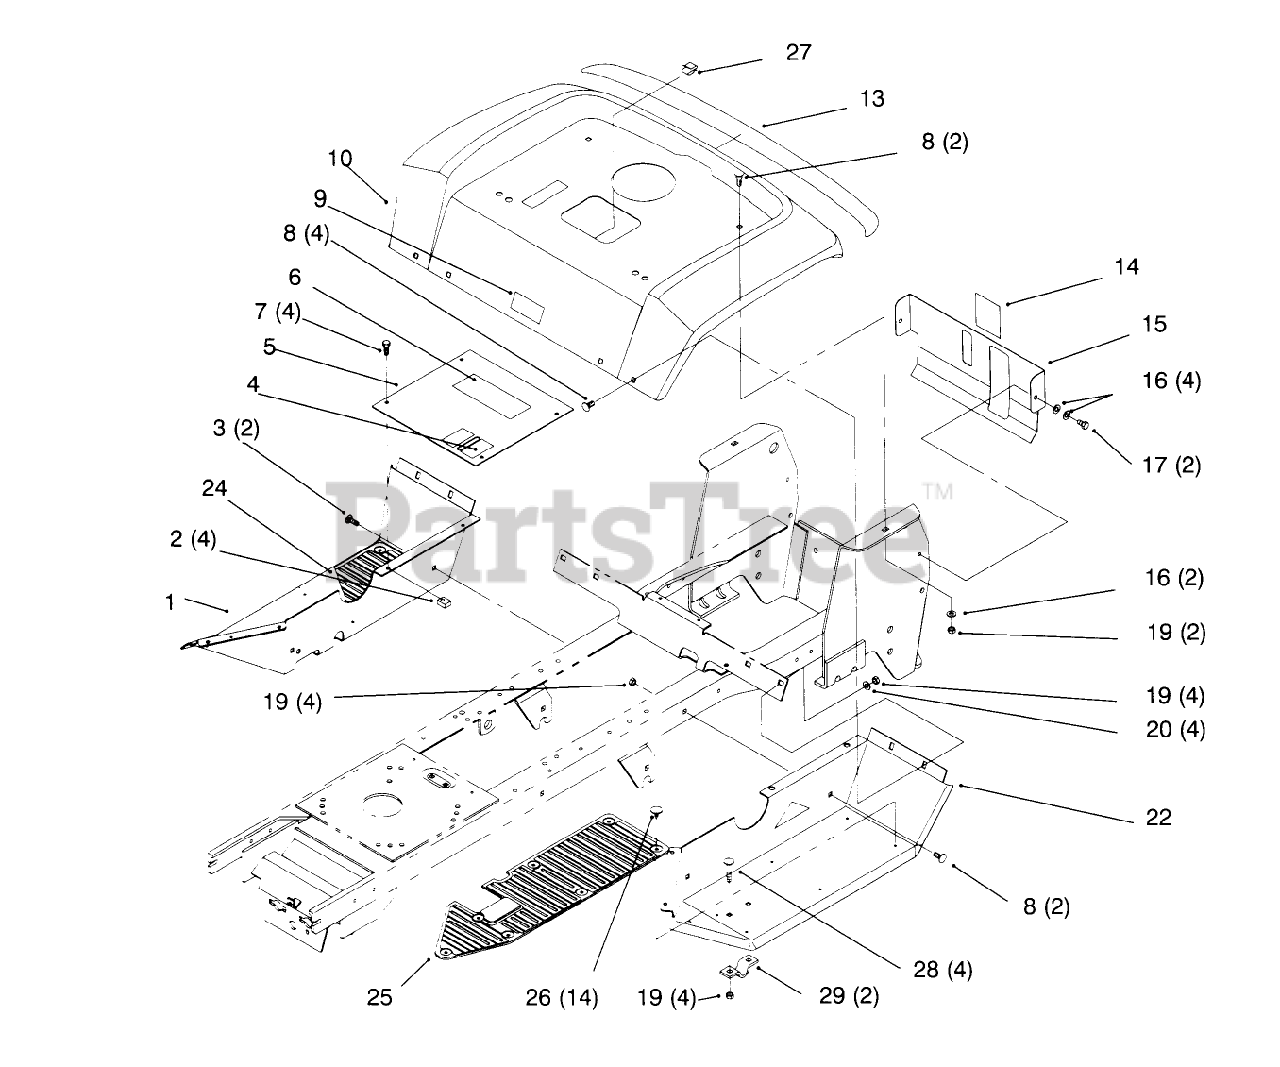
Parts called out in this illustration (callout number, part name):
1	FOOTREST-RH
3	SCREW-CARR
4	DECAL - HOC
5	PLATE/DECAL ASM-FOOTREST
6	DECAL-DANGER
7	SCREW-HH
8	BOLT-CARR
9	DECAL - USA
13	DECAL - REAR FENDER
14	DECAL-LEVEL, FUEL
15	COVER-REAR
16	WASHER-PLAIN
17	SCREW
19	NUT-LOCK, NI
20	WASHER-FLAT
22	LH FOOTREST
22	FOOTREST-LH
24	FOOTPAD-RH
24	FOOT MAT-RH
25	FOOTPAD-LH
25	FOOT MAT-LH
26	FASTENER-PANEL
27	CLIP-RETAINER, WIRE
29	CLAMP
